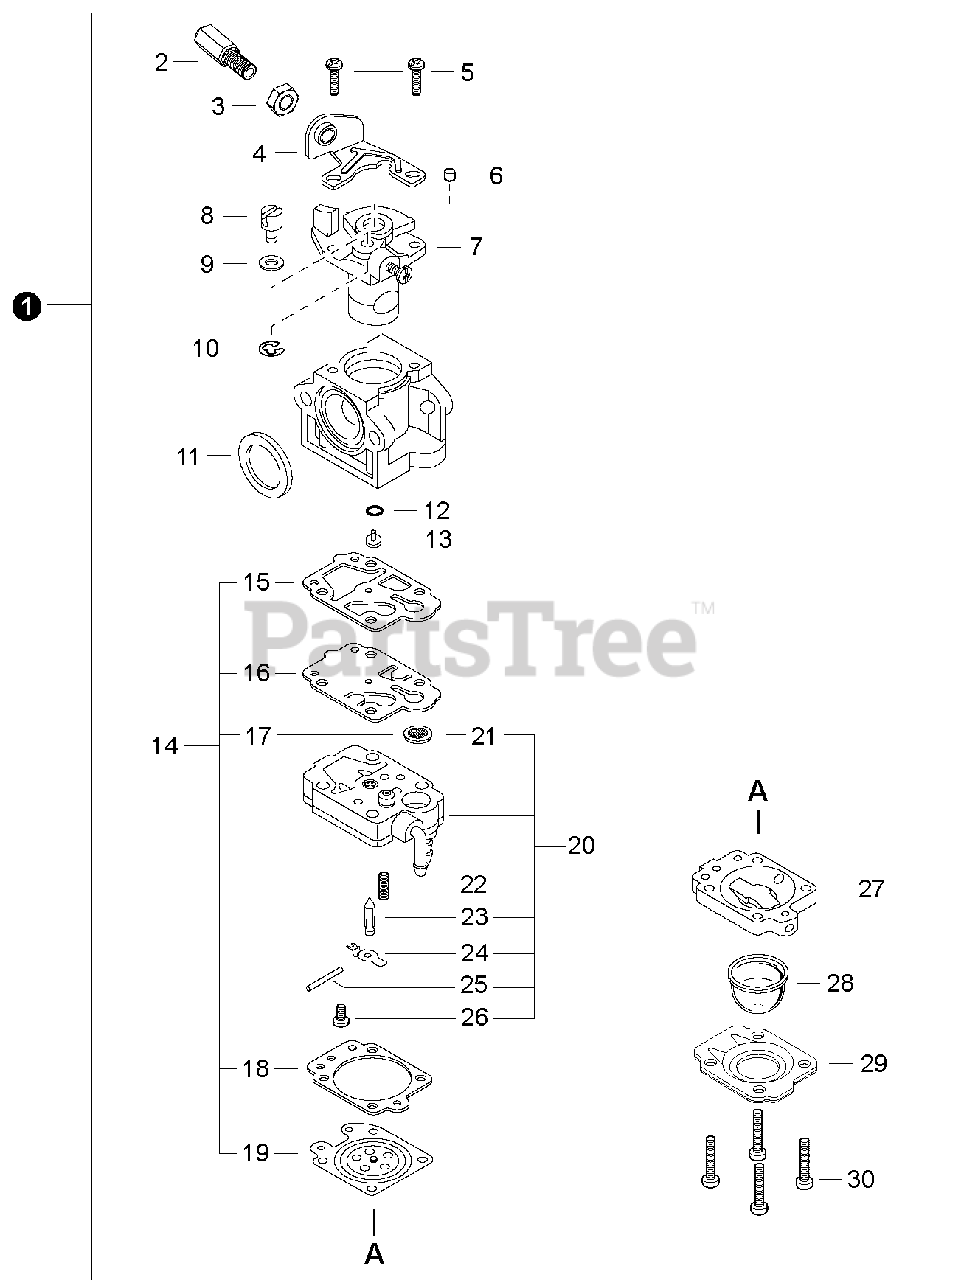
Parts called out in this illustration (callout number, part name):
1	CARBURETOR - WYJ-396
2	ADJUSTER, THROTTLE CABLE
3	NUT, ADJUSTER LOCK M7
4	BRACKET, THROTTLE CABLE
5	SCREW
6	PLUG
7	VALVE ASSY, THROTTLE
8	SWIVEL
9	WASHER
10	E-RING
11	RING, PACKING
12	O-RING
13	JET, MAIN
14	GASKET / DIAPHRAGM KIT
15	GASKET, PUMP
16	DIAPHRAGM, FUEL PUMP
17	SCREEN, FUEL INLET
18	GASKET, METERING DIAPHRAGM
19	DIAPHRAGM, METERING
20	BODY ASSY, PUMP
21	SCREEN, FUEL INLET
22	SPRING, METERING LEVER
23	VALVE, INLET NEEDLE
24	LEVER, METERING
25	PIN, METERING LEVER
26	SCREW
27	BODY ASSY, PURGE
28	BULB, PURGE
29	RETAINER, PURGE BULB
30	SCREW
